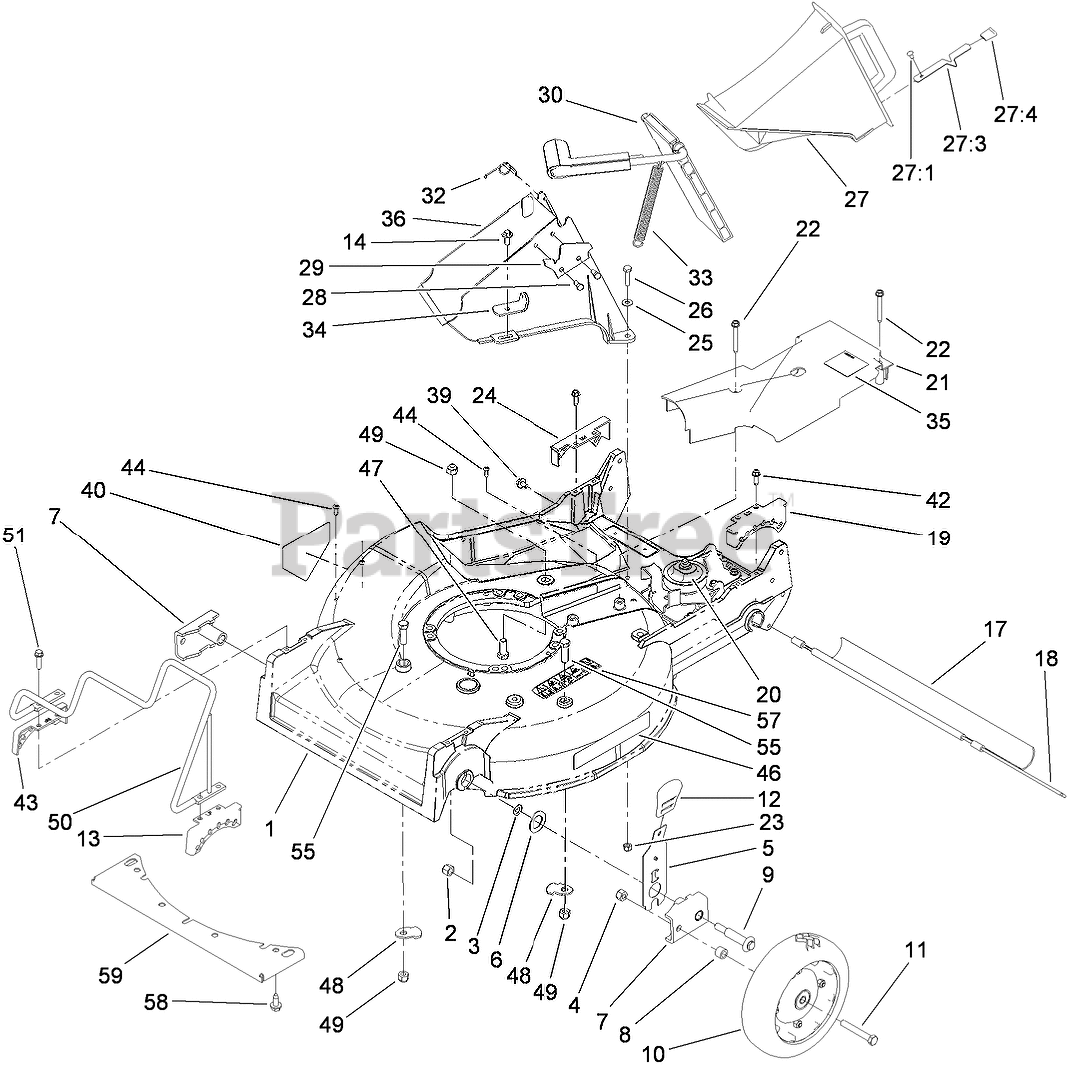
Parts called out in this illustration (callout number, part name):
1	HOUSING
2	NUT-LOCK
3	WASHER
4	NUT-LOCK, CONE
5	FRONT SPRING ARM ASM
6	WASHER-THRUST
7	ARM-PIVOT, FRONT
8	SPACER-WHEEL
9	SCREW-SHOULDER
10	Wheel and Tire ASM
11	SCREW-HH
12	KNOB-HOC
13	QUADRANT-FRONT, LH
14	SCREW-HWH
17	SHIELD-TRAILING
18	ROD-SHIELD
19	QUADRANT-REAR, LH
20	GEAR CASE ASM
21	COVER-BELT
22	SCREW-HWHTF
23	NUT-LOCK, NI
24	QUADRANT-REAR, RH
25	WASHER-FLAT
26	SCREW-HH
27	DISCHARGE PLUG ASM
27:1	RIVET-HEAD, FLAT
27:3	LATCH-PLUG, DISCHARGE
27:4	GRIP-LATCH
28	SCREW-PLASTITE
29	LATCH-PLATE
30	DISCHARGE DOOR ASM
32	RETAINER-DOOR
33	SPRING-DOOR
34	BRACKET-SPRING
35	DECAL-GREASE
36	TUNNEL-DISCHARGE
39	SCREW AND WASHER ASM
40	DECAL-DANGER
42	SCREW-HWHTF
43	QUADRANT-FRONT, RH
44	SCREW-PPH
47	SCREW-HH
48	SHIELD-RETAINER
49	NUT-LOCK, NI
50	GUARD-ENGINE
51	SCREW-HWHTF
55	SCREW-HH
57	DECAL-DANGER
58	SCREW-HWHTF
